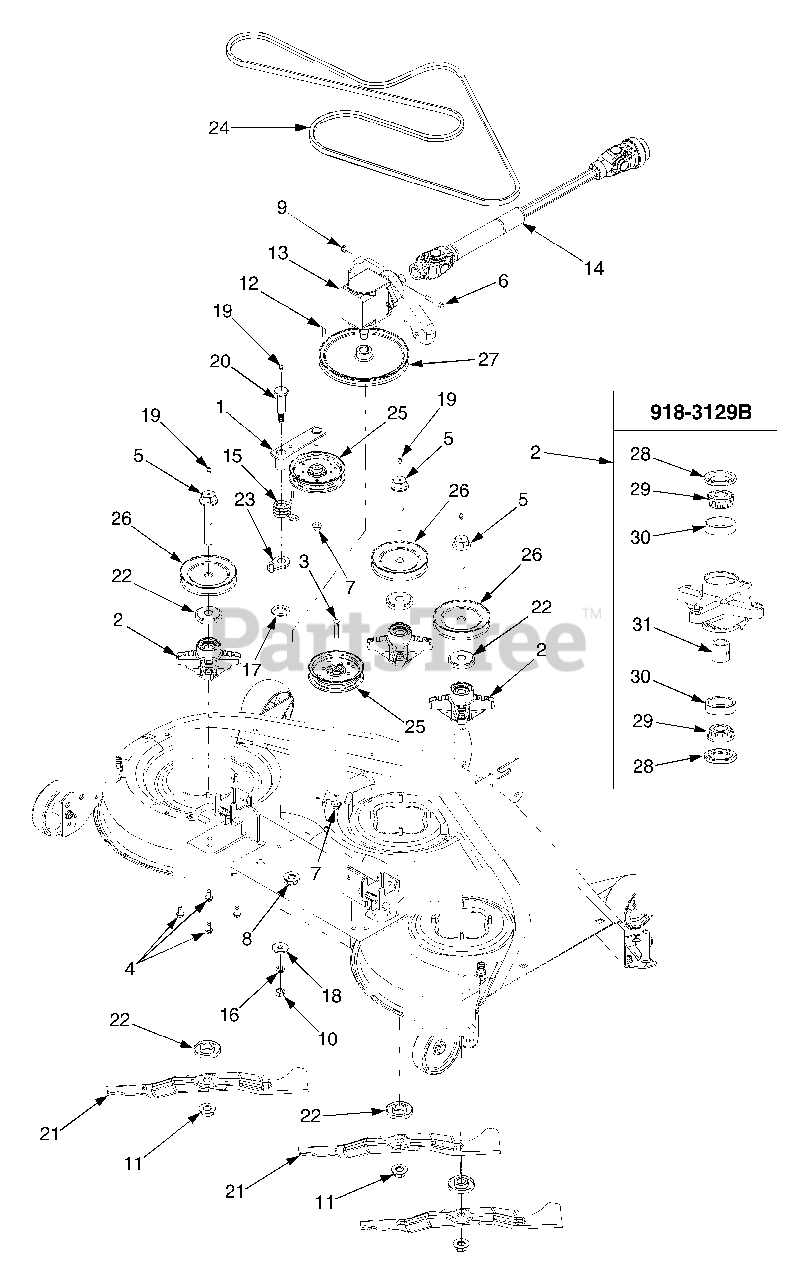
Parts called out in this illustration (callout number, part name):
2	Spindle Assembly
3	Screw, Hex Cap, 3/8-16 x 1.5 GR5
4	Screw, Hex Wash. Hd. Tapp 5/16-18 x .7
5	Bolt, Spindle, 3/4-16 x 4.25
6	Screw, Socket Hd. 5/16-18 x 1.75 GR5
7	Nut, Hex Insert Lock, 3/8-16 GRF
8	Nut, Flange, 58-18
9	Nut, Hex Insert Lock, 5/16-18 GR5
10	Nut, Hex, 7/16-14 GR2
11	Nut, Hex Flange, 3/4-16
12	Key, Hi Pro, 3/16 x 3/4
13	Drive, Right Angle
14	Shaft, Drive
15	Spring, Torsion
16	Washer, Lock, 7/16
17	Washer, Flat, 1.031 x 1.62 x .095
18	Washer, Flat, .45 x 1.38 x .134
19	Fitting, 3/16 Drive Lube
20	Bolt, Shoulder, .68 x 2.11:7/ 16-14
21	Blade, 2 in 1, 17.9"
22	Spacer, Deck Spindle
23	Retainer, Spring
24	Belt, V 1/2 x 111.5"
25	Pulley, Flat Idler, 4.25 OD
26	V-Pulley, 4.0"
27	Pulley, Drive
28	Seal, Oil, 1.25 x 1.874 x .25
29	Bearing, Cone
30	Cup, Bearing
31	Spacer, Bearing
